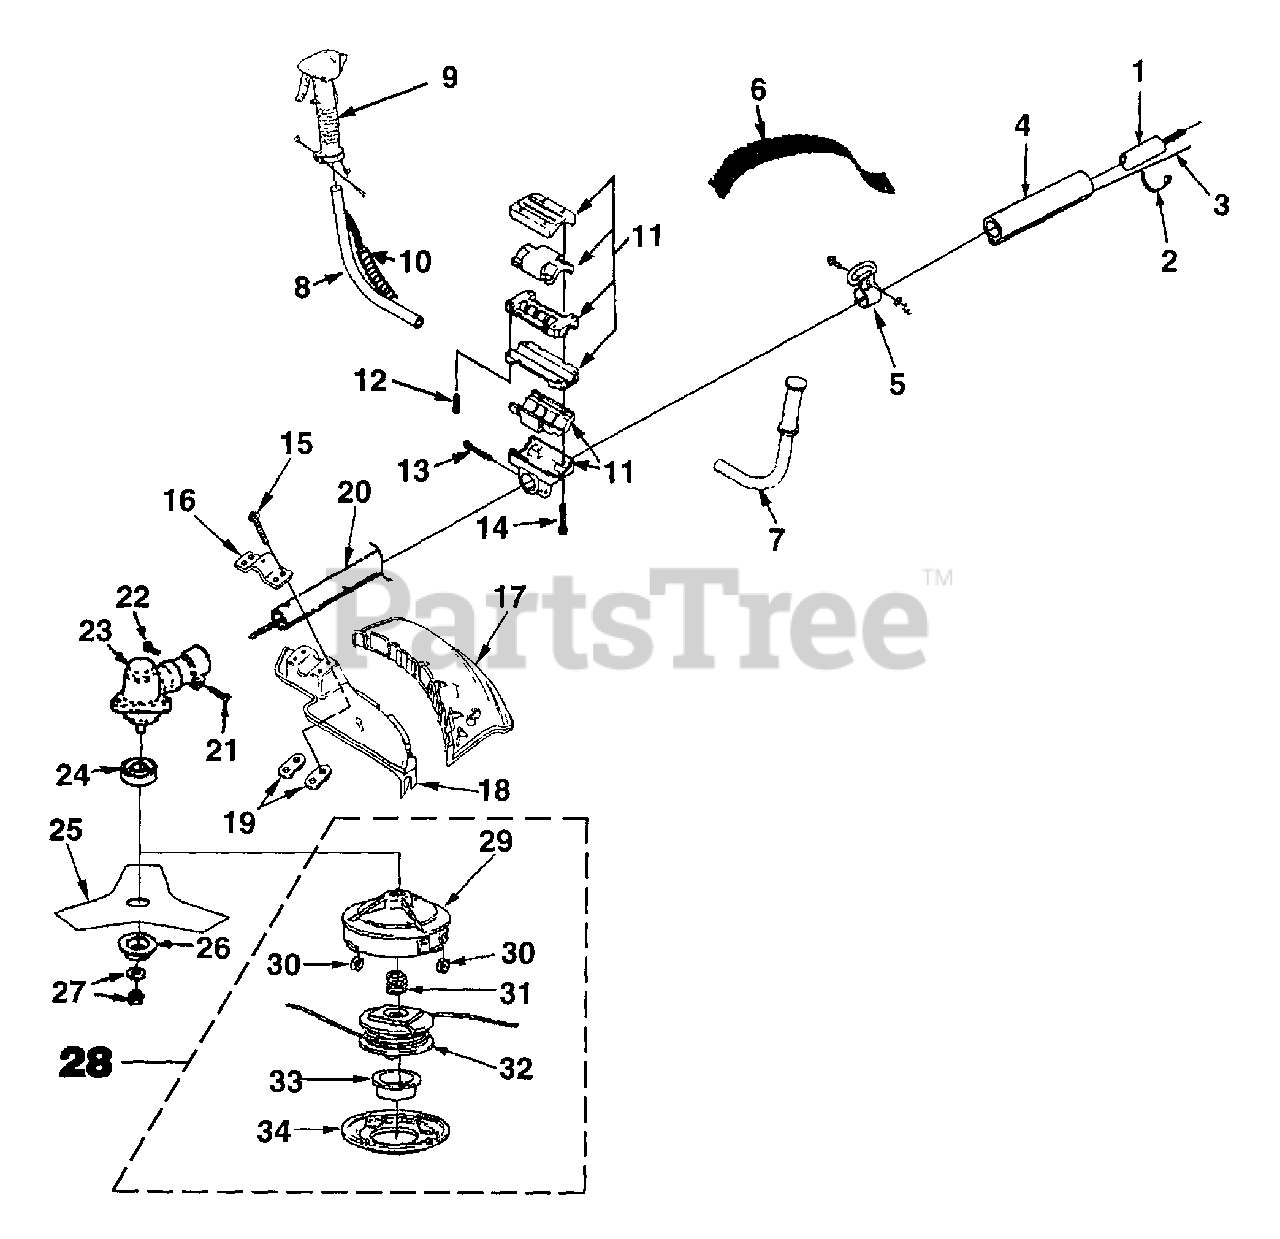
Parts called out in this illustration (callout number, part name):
1	DRIVE SHAFT
2	CABLE-Tie
3	THROTTLE CABLE
4	HIP PAD
5	BRACKET-Hanger
6	SHOULDER HARNESS (Full)
7	HANDLE BAR & GRIP (Left)
8	HANDLE BAR & CONTROL GRIP
9	BIKE CONTROL GRIP
10	SLEEVING
11	BRACKET-Handle Bar
12	SCREW-Soc Hd
13	SCREW-Hex Hd
14	SCREW-Hex Hd
15	SCREW-Mach Tr Hd (10-24 x .750)
16	CLAMP
17	STRING SHIELD
18	BLADE GUARD
19	MOUNTING PLATE
20	DRIVE SHAFT HOUSING
21	SCREW-Cap Socket Hd (1/4-20 x 7/8")
22	SCREW-Sems Hex Hd
23	GEAR HEAD
24	WASHER-Flanged
25	BLADE-Tri-Arc
26	WASHER-Cupped
27	NUT-Lock
28	STRING HEAD
29	HOUSING, String
30	EYELET
32	SPOOL W/String
33	BUTTON
